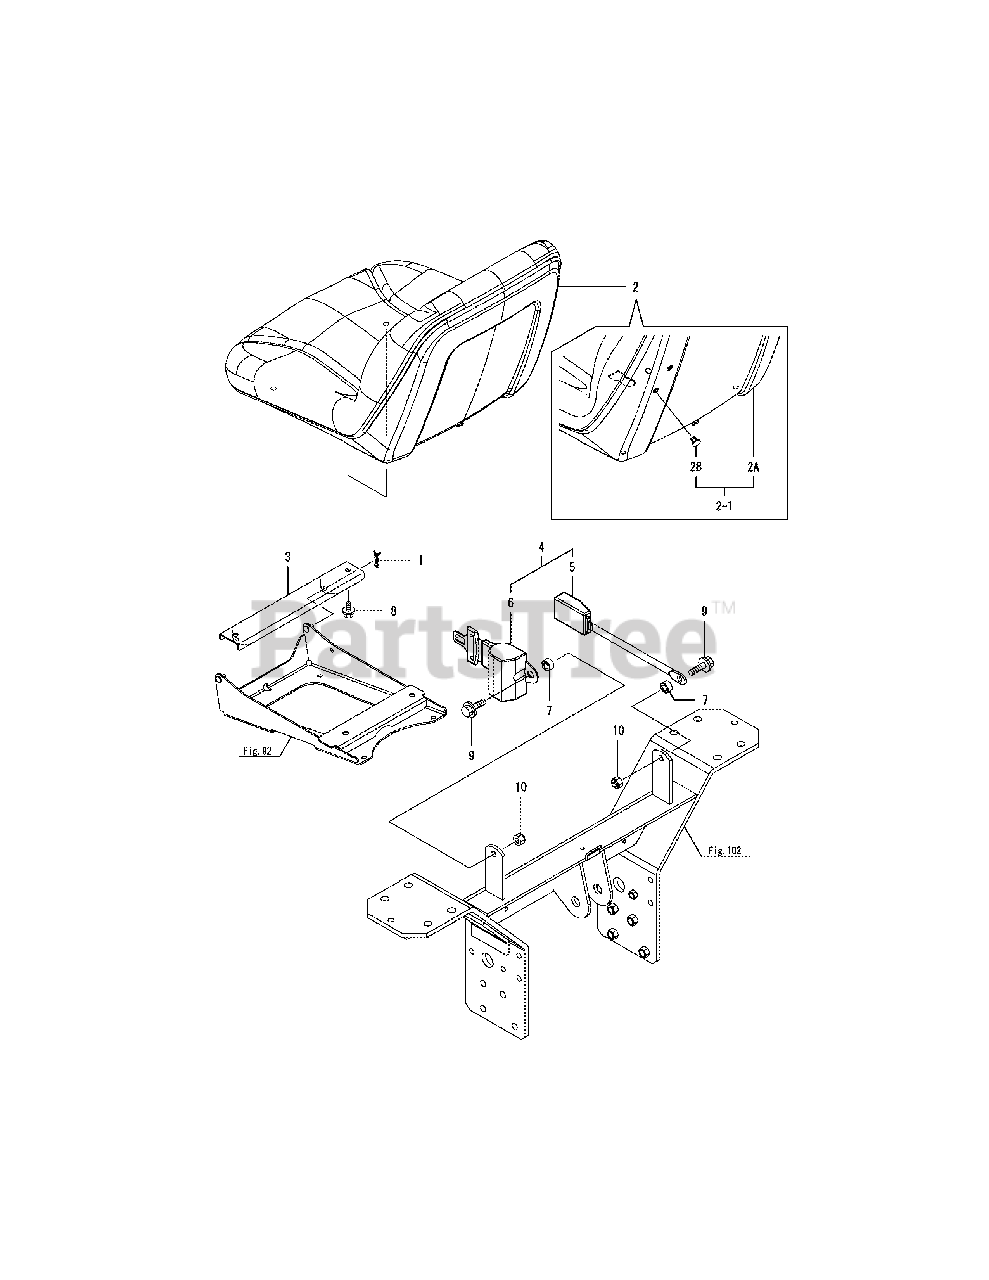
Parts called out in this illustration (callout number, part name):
1	Pin 8,Come-Off Snap
2	Seat Assy, Operator
2-1	Seat Asy
2A	Seat Assy, Operator
2B	Nut Plug
3	Hinge, Seat Cmp
4	Seat Belt Assy
5	Seatbelt Assy, L
6	Belt R, Safety Cmp
7	Collar, Seat Belt
8	Bolt M 8X 16 Plated
9	Bolt M10X 35 Plated
